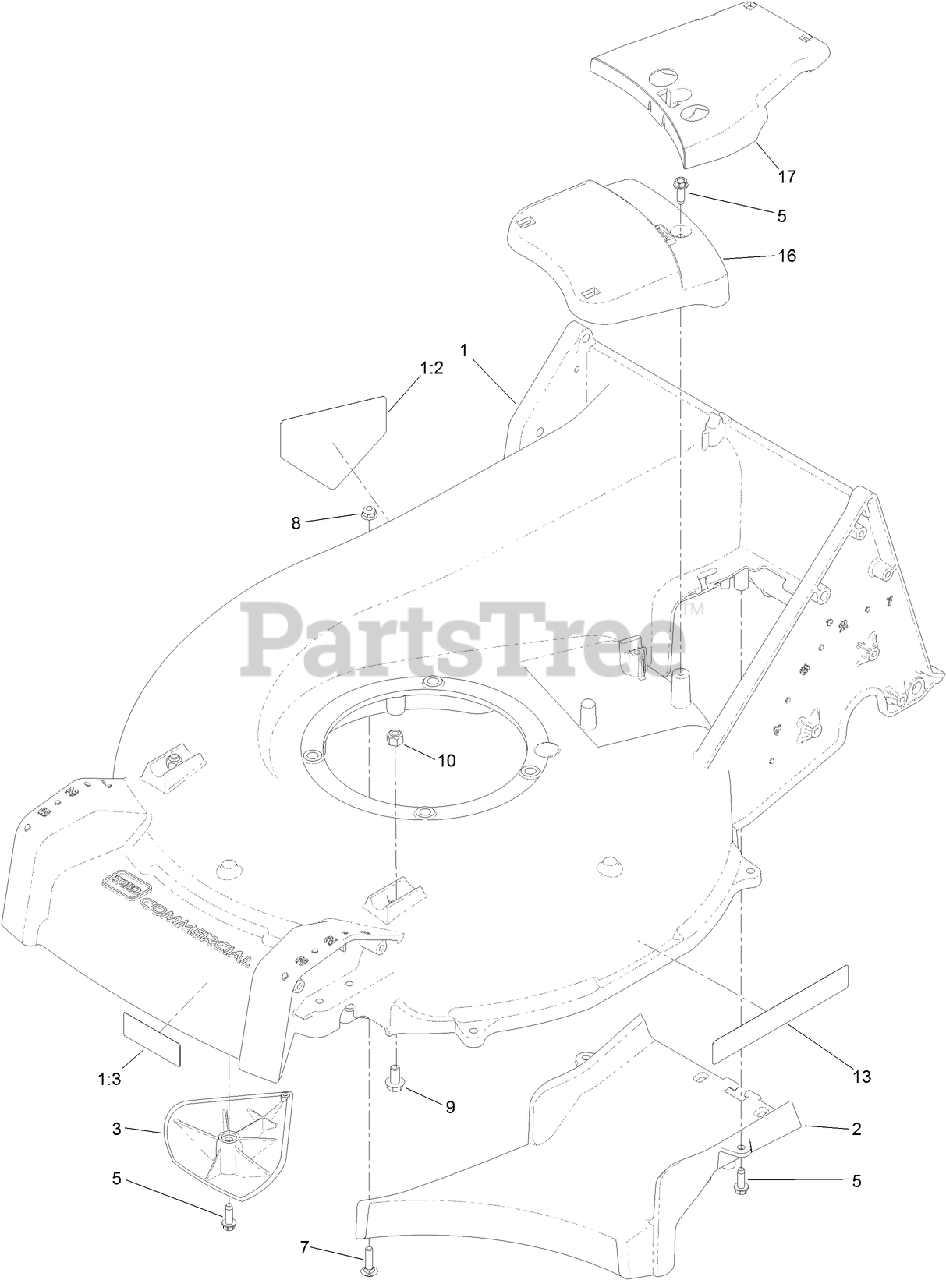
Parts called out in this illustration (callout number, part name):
1	HOUSING ASM
1:2	DECAL-DANGER
1:3	DECAL-BLADE
2	FLOOR-CHUTE
3	KICKER
5	SCREW-HWHTF
7	SCREW-CARR
8	NUT-HF
9	SCREW-HHF
10	NUT-LOCK, NI
13	DECAL-RECYCLER
16	COVER-BELT, FRONT
17	COVER-BELT, REAR
